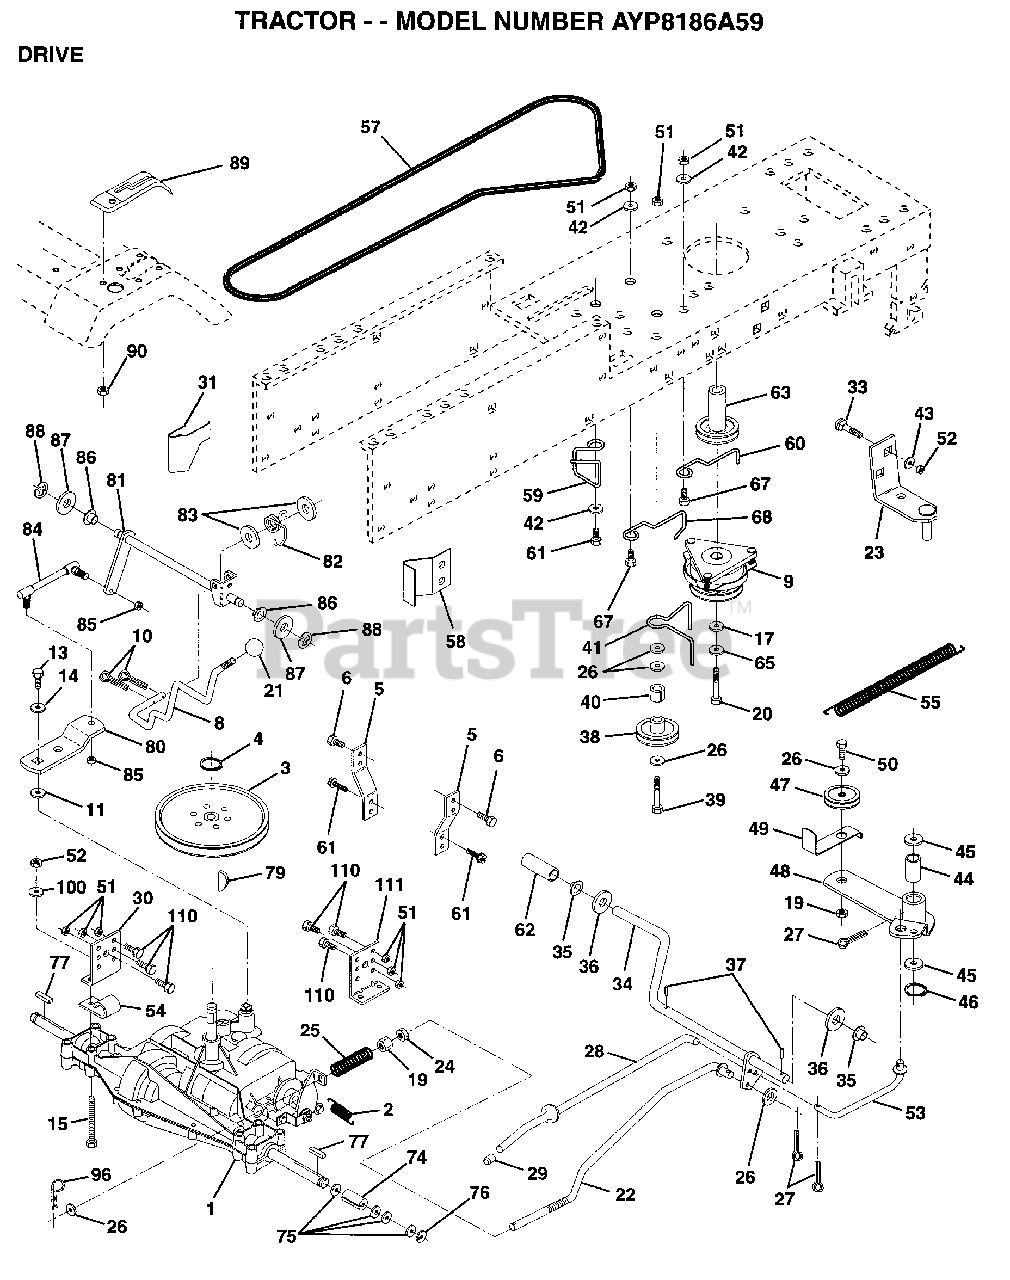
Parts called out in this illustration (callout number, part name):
1	TRANSAX. PRLES.
3	PULLEY TRANSAXLE
4	RING
5	STRAP TORQUE
6	SCREW
10	PIN COTTER 1/8
11	WASH-SHFT PLT LT
13	BOLT.1/4-28.W/PAT
14	WASHER PM
15	BOLT HEX
17	WASHER
19	NUT
21	KNOB T (1/2-HOLE)
22	ROD.ASM.BK.44.MWR
23	BRACKET.ASM.MTG
24	NUT
25	"SPRING,ROD BRAKE"
26	WASHER
27	COTTER PIN
28	ROD.BRAKE.PARK.LT
30	BRKT TRANS LH
31	KEEPER BELT LH
33	BOLT
34	SHAFT.PEDAL.FOOT
35	NYLON BEARING
36	WASHER LT
38	PULLEY.IDLER.FLAT
39	BOLT
40	SPACER T
41	BELT KEEPER LT
42	WASHER
43	WASHER T
44	"LY, BEARING"
45	WASHER LT
46	KLIP RING
48	ARM IDLER
49	RETAIN BELT
53	"LINK, CLUTCH T"
54	CLIP T
55	"SPRING, RETURN LT"
57	BELT.GRDRV.94.75
58	"KEEPER,BELT RH"
59	KEEPER BELT CNTSP
60	KEEPER BELT ENGLH
61	SCREW
62	PEDAL COVER T
63	PULLEY ENGINE
65	PULLEY ENGINE
65	LOCKWASHER
67	BOLT
68	"KEEPER,BLT ENG LT"
74	SPACER HYT
75	WASHER
76	E RING HYT
77	SQ KEY STD
80	"ARM,SHIFT"
81	"SHAFT,SHIFTER"
82	"SPRING,TORSION"
83	WASHER
84	"ROD,TIE "
85	NUT 1/4-28
86	BUSHING
87	WASHER D
88	KLIP RING
89	CONSOLE SHIFTER
90	NUT
96	RETAINER M
100	WASHER M
111	BRKT TRANS RH
